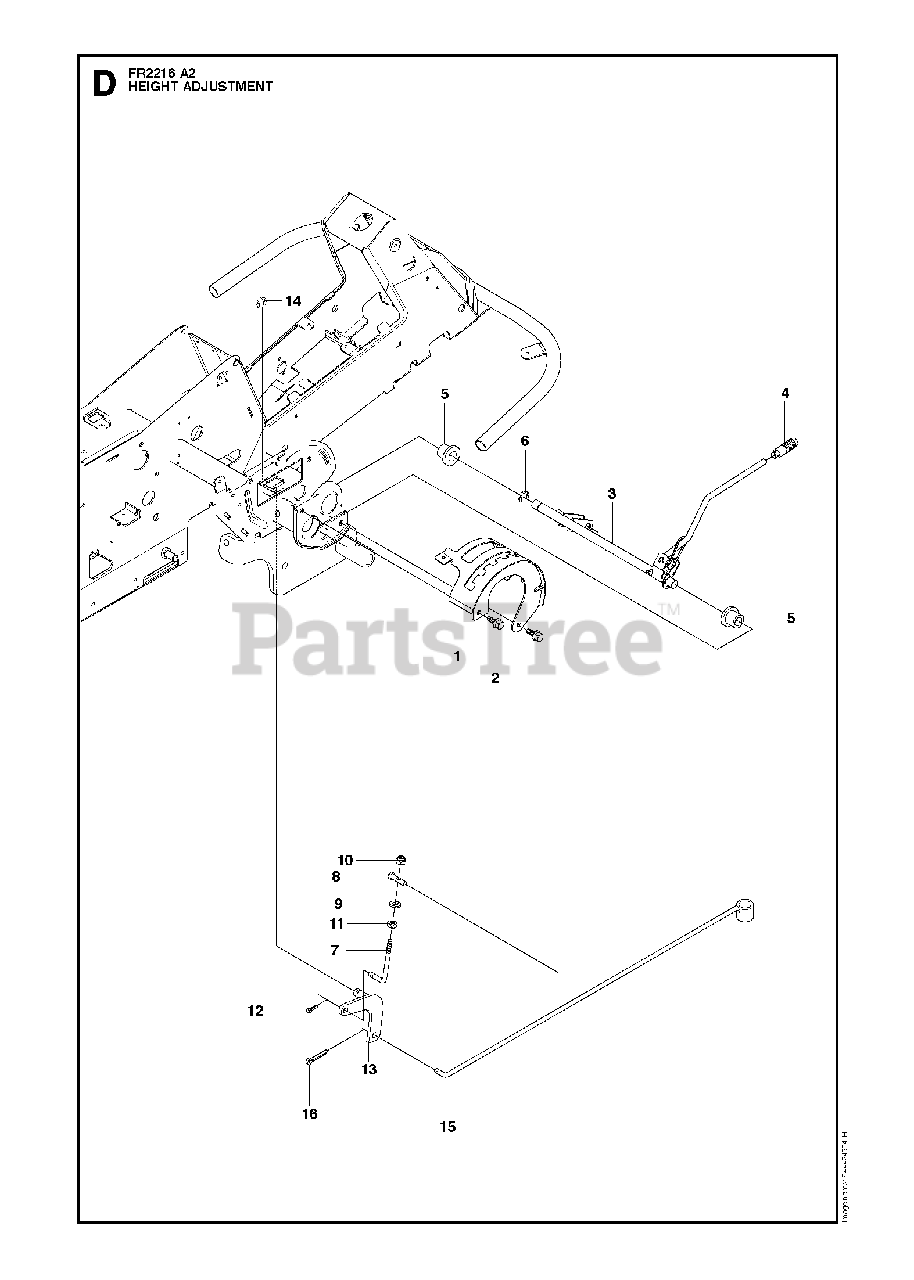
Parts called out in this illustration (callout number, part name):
4	GEAR STICK KNOB
5	BUSHING
9	WASHER
10	LOCKNUT M8
11	NUT
12	SPLIT PIN
14	RETAINING RING
15	CLUTCH ROD
16	SPLIT PIN
